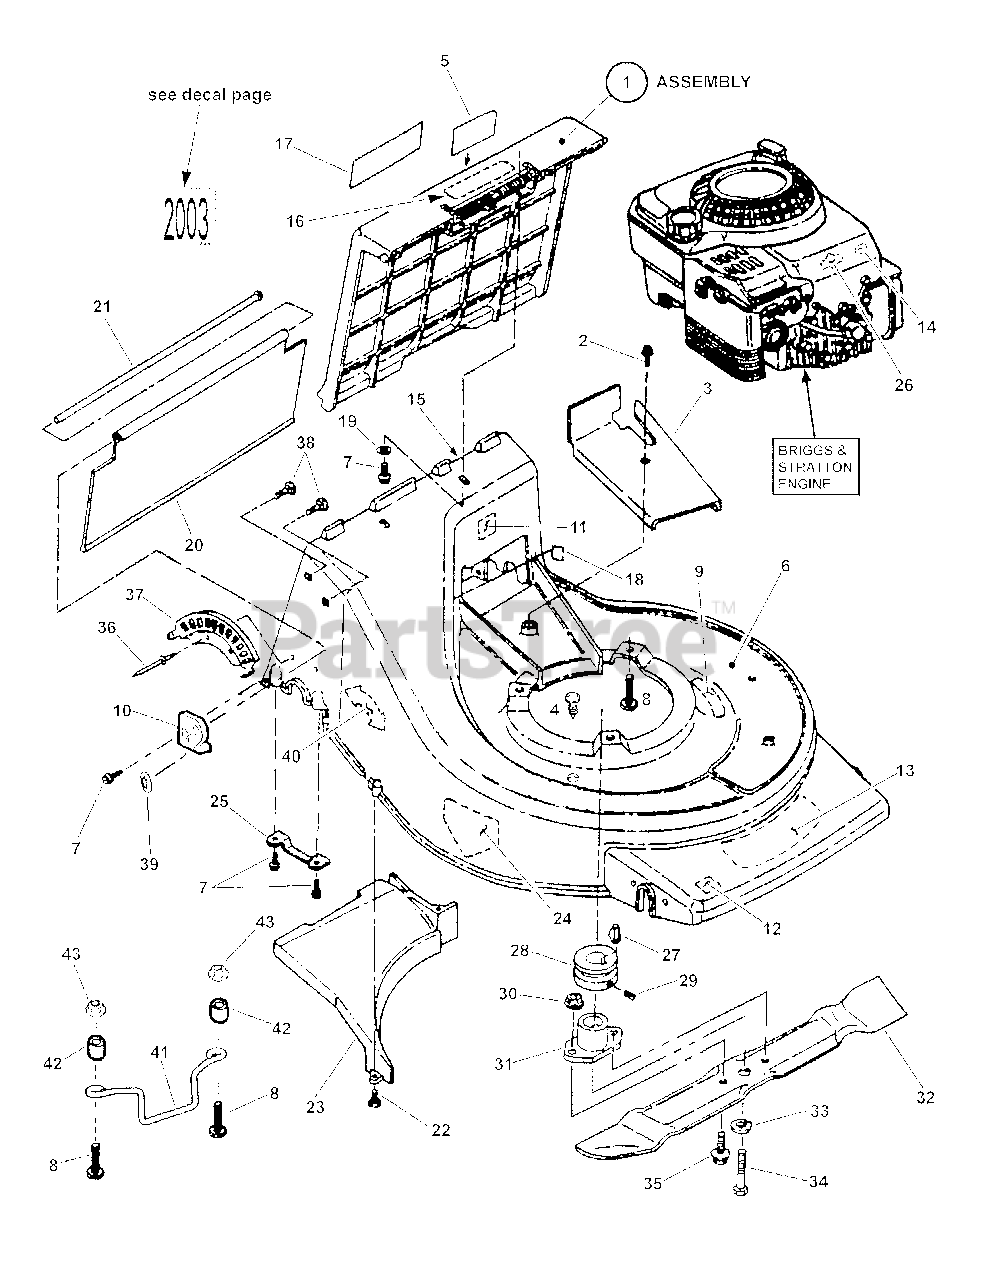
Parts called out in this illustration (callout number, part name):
1	ASSEMBLY, Discharge Door
2	SCREW, #10-24 x 1-1/2" Slotted Hex Washer Head Self-Tap
3	COVER, Belt/Tie Bar
4	HOLE PLUG, Polyethylene
5	DECAL, Warning 1997
6	DECK, 21" Cast Aluminum Rocker
7	SCREW, 1/4-20 x 5/8" Hex Washer Self-Tap
8	SCREW, 3/8-16 x 2" Hex Head Self-Tap
9	DECAL, Warning (Deck)
10	BRACKET, RH Trailing Shield Pivot Rod
11	DECAL, Sound 100 dB (Euro)
12	DECAL, Euro Community (CE)
13	LOGO, SNAPPER Cast Aluminum Series
14	DECAL, Spark Plug International Symbol (Euro)
15	DECAL,Deck/Chute International Warning (Euro)
16	DECAL, Chute Deflector Warning
17	DECAL, Convertible Mower
18	DECAL, Patent Numbers
19	WASHER, 1/4" Flat
20	SHIELD, Trailing
21	ROD, Trailing Shield Pivot (Long)
22	SCREW, #10-24 x 5/8" Hex Washer Self-Tap
23	BAFFLE, Discharge
24	DECAL, Danger, Cut Finger
24	DECAL, Warning (Deck) (Euro)
25	SUPPORT, Rear Axle
26	LOGO, Briggs & Stratton
27	KEY, Hi-Pro #HP506 (Briggs engine)
27	KEY, Hi-Pro #HP-505 (Kawasaki engine)
28	PULLEY, Traction Drive (25mm x 2-1/8" O.D.)
28	PULLEY, Traction Drive (.88 x 2.12 O.D.)
29	SCREW, 5/16-18 x 5/16" Hex Socket Set
30	NUT, 3/8-16 Hex Nyloc
31	HUB, 25 mm Blade Drive
31	HUB, 7/8" I.D.Blade Drive
32	BLADE, 21" Mulching/Bagging
33	WASHER, 3/8" Split Lock (Heavy)
34	SCREW, 3/8-24 x 1-3/4 Hex Head Cap, GR 5
35	BOLT, 3/8-16 x 1-1/4" Hex Flange Lock
36	RIVET, 3/16 x 1/2" Steel
37	PLATE, Height Adjust
38	BOLT, 5/16-18 x 1" Square Neck Carriage, GR 5
39	PUSHNUT, 1/4" Black
40	DECAL, Height Control Instr. (Euro)
41	GUIDE, Belt
42	SPACER, .390 I.D. x 3/4" O.D. x 1/2" Long
43	NUT, 3/8-16 Hex Flange Lock
